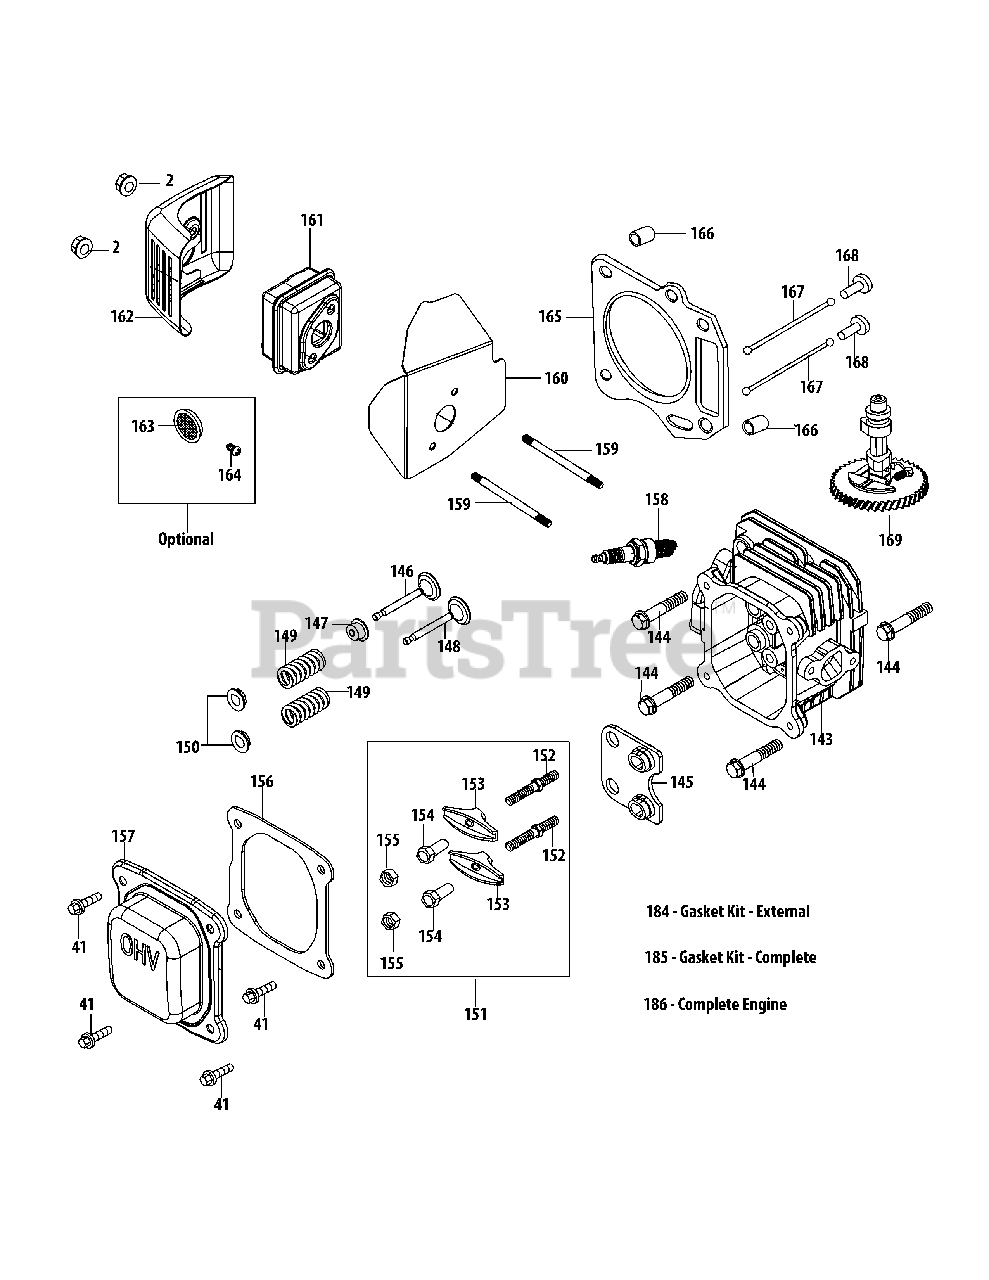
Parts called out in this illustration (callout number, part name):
2	Nut M6X10Mm
41	Bolt M6X14
143	Cylinder Head Svc Kit
143	Cylinder Head Asm
144	Bolt M8X54
145	Push Rod Guide
146	Valve Kit
147	Intake Valve Seal
148	Valve Kit
149	Valve Spring
150	Valve Spring Retainer
151	Rocker Arm Assembly
152	Rocker Arm Stud
153	Rocker Arm
154	Fulcrum Nut
155	Jam Nut
156	Valve Cover Gasket
157	Valve Cover
158	Spark Plug
159	Muffler Stud M6X68
159	Muffler Stud Asm
160	Muffler Gasket
161	Muffler Assembly
162	Muffler Shield
163	Spark Arrestor
164	Spark Arrestor Screw
165	Cylinder Head Gasket
166	Cylinder Head Dowel Pin 10×16
167	Push Rod Kit
168	Tappet
169	Camshaft Assembly
184	Gasket - External
185	Gasket Kit - Complete
186	Complete Engine
